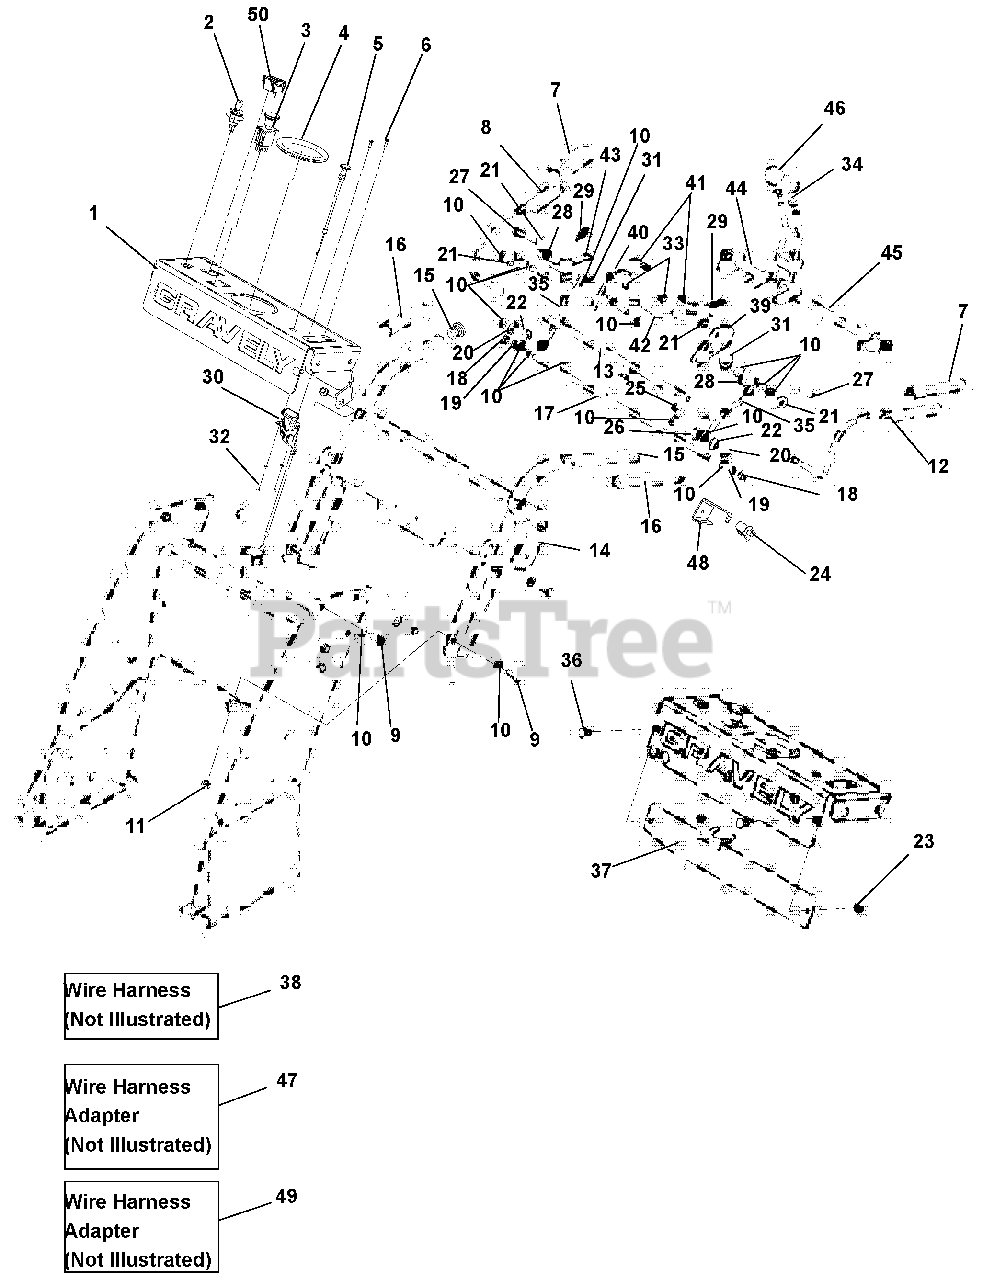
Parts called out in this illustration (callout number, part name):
1	ASSM, CE HYDRO CONSOLE
2	SWITCH, TWO POSITION KEY (988323)
2	SWITCH, THREE POSITION KEY (988324, 325)
3	SWITCH, CLUTCH w/GRAPHIC
4	TRIM, RUBBER EDGE 12"
5	CABLE, CHOKE 48"
6	SCR-PANHDSLT 8-32X.50 YWZC
7	GRIP, CLUTCH LEVER, LH AND RH
8	WMT-RH LEVER-OP
9	BOLT, HEX .38-16 X 1.00 GR5 Y
10	WASHER, .406 X .813 X .065 FLAT Y
11	LOCKNUT, .38-16 NYLOC Y
12	WMT-LH LEVER-OP
13	WMT-PIVOT TUBE
14	CONSOLE, LOWER PG CE W/DECAL
15	CAPLUG, HANDLEBAR
16	GRIP, HANDLEBAR
17	ROD, SPEED CONTROL
18	NUT-HEX .375-24 YWZC GR2
19	WASHER-LOCK .38 X .094 REG
20	WASHER-FLAT-NYL .52 X 1.00 X .08
21	WASHER-FLAT-STL .406 X 1.00 X .188
22	BUSHING-FLANG .385 X .500 X .875 X .31
23	NUT-LOCKING-NYLON .312-18
24	SWITCH, SEAT OVER RIDE (N.O.)
25	SCREW-TAP 10-24 X .50 HWH
26	ROD END, .38 RH
27	BOLT - HEX .38-16 X 2.00 GR5
28	SPRING-COMPRESSION .045 X .600 X .750
29	SPRING-TENSION .041 X .500 X 1.750
30	CABLE, THROTTLE - 49.5
31	WASHER-FLAT-STEEL .50 X 1.25 X .083
32	NUT-LK-NYL 8-32 W/INSTR YWZC
33	NUT-LK-CTR .375-16
34	NUT-HEX .38-16
35	ROD, STEERING LINK
36	BOLT-RDHDSQNK .31-18X.75 G5
37	BRACKET, REMOTE ROV HYDRO
39	LATCH-LH THUMB
40	LATCH-RH THUMB
41	GRIP, THUMB LATCH
42	LEVER, HAND CONTROL LH
43	LEVER, HAND CONTROL RH
44	WELDMENT, RH LEVER
45	WELDMENT, LH LEVER
46	KNOB,BALL -BLACK 1.47" .375-16
48	BRKT, OPC SWITCH
49	HARNESS, NMIR ADAPTER CE
50	METER, HOUR SMART SENSE W/O SV
